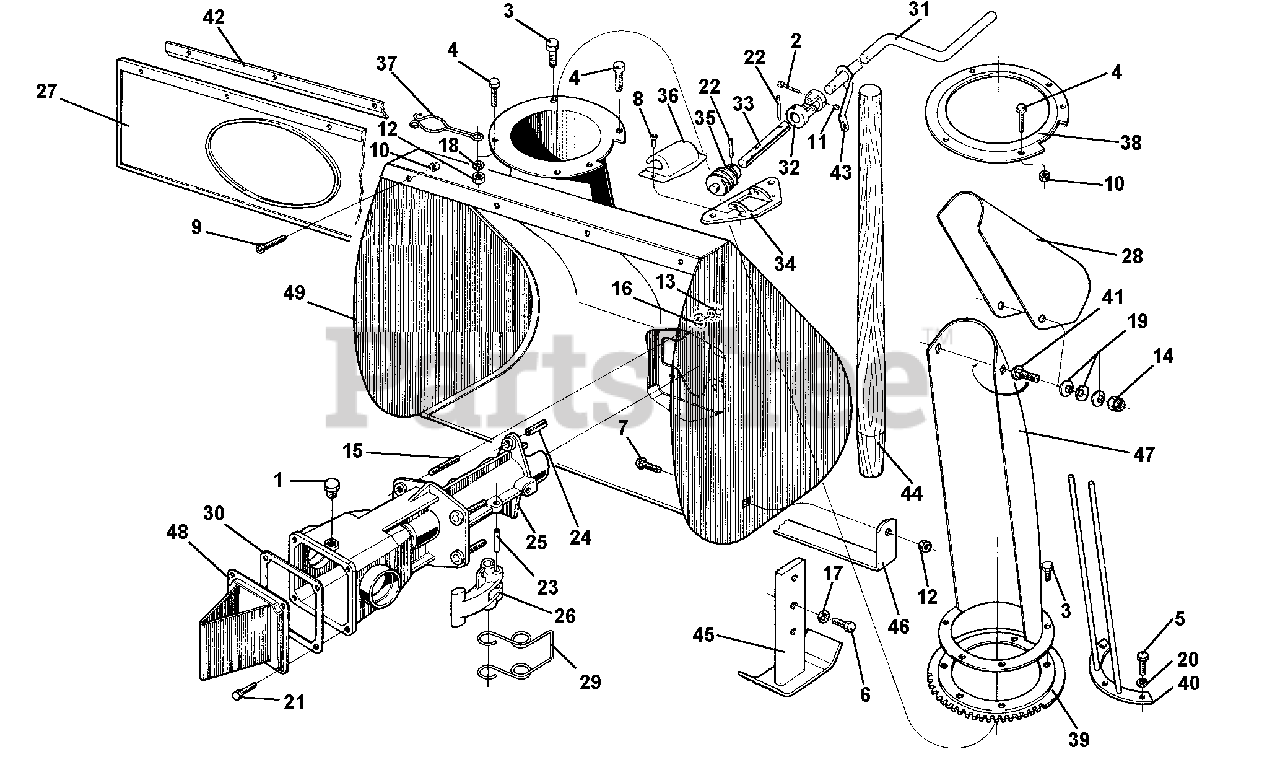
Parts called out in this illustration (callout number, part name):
1	PLUG 1/4 GAS
2	SCREW TE M4 X 35
3	SCREW M6 X 12
4	SCREW M6 X 25
5	SCREW TE M6 X 16
6	SCREW TE M10 X 16 UNI 5739-8G
7	SCREW M6 X 20
8	SCREW TSVEI M4 X 10
9	SCREW M6 X 16
12	NUT, SELF LOCKING M6
13	NUT, SELF LOCKING M8
14	NUT, SELF LOCKING M10 LOW
15	STUD M8 X 32 X 14 X 14
16	WASHER, FLAT 8.4
17	FLAT WASHER 10.5 X 21
18	WASHER, FLAT 6.4
19	SPRING 10.2 X 28 X 1.5
20	WASHER, LOCK 6.4
21	SCREW M6 X 12
22	PIN, LOCKING 5 X 30
23	SPIRAL PIN 8 X 40
24	LOCKING PIN 12 X 26
25	SNOW THROWER SUPPORT
31	FUNNEL CONTROL ROD
35	HELICAL GEAR
37	SPRING FOR STICK
38	FLANGE FOR RING
40	GRID FOR CHUTE 1985
41	SCREW M10 X 25
42	MUDFLAP HOLDER
43	ROD SUPPORT
46	COVER SLIDE
